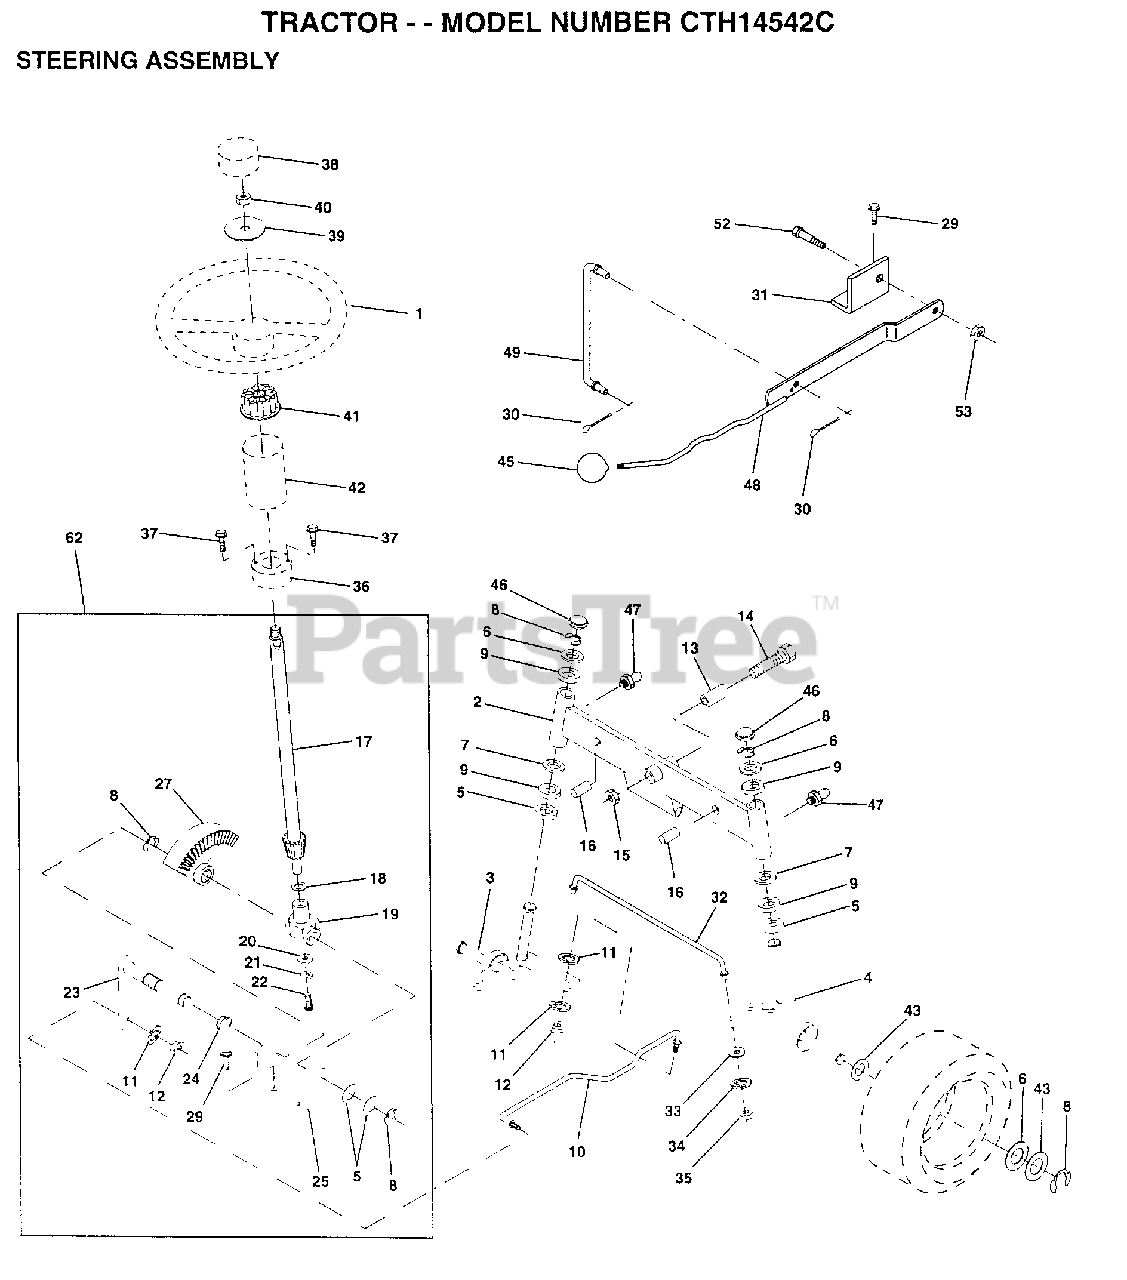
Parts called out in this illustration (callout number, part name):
1	WHEEL STR AYP BLK
2	AXLE ASM FRONT
3	SPINDLE LH
4	SPINDLE RH
5	WASHER .T
6	WASHER
7	WASHER
8	RING
9	COL. SRTG. BEAR.
11	LOCKWASHER
13	BEARING
14	BOLT HEX 5/8-11
15	"NUT-LOC,FLANGE LT"
16	AXLE PIN
17	STEERING SHAFT
18	THRUST WASHER
19	SUPPORT.SHAFT
21	LOCKWASHER
22	SCREW.SCKTHD.CAP
24	NYLINER T
25	"BRKT,STEERING"
27	GEAR SECTOR
29	SCREW
30	COTTER PIN
31	BRKT.PVT.MAN.LVR.
32	ROD.TIE.19.75
33	WASHER M
34	LOCKWASHER
35	NUT.LOCK.5/16-24
36	BUSHING.STRG.3/4
37	"SCREW-TT,10-32 FL"
38	CAP STEER AYP
39	WASHER
41	ADAPTER LT
42	BOOT SHAFT STEER
43	WASHER
45	CONTROL KNOB LT
46	CAP
47	ZERK M
48	LEVER.ASM.CLUTCH
49	LINK CLTCH W/NUTS
52	"BOLT, SHOULDER LT"
